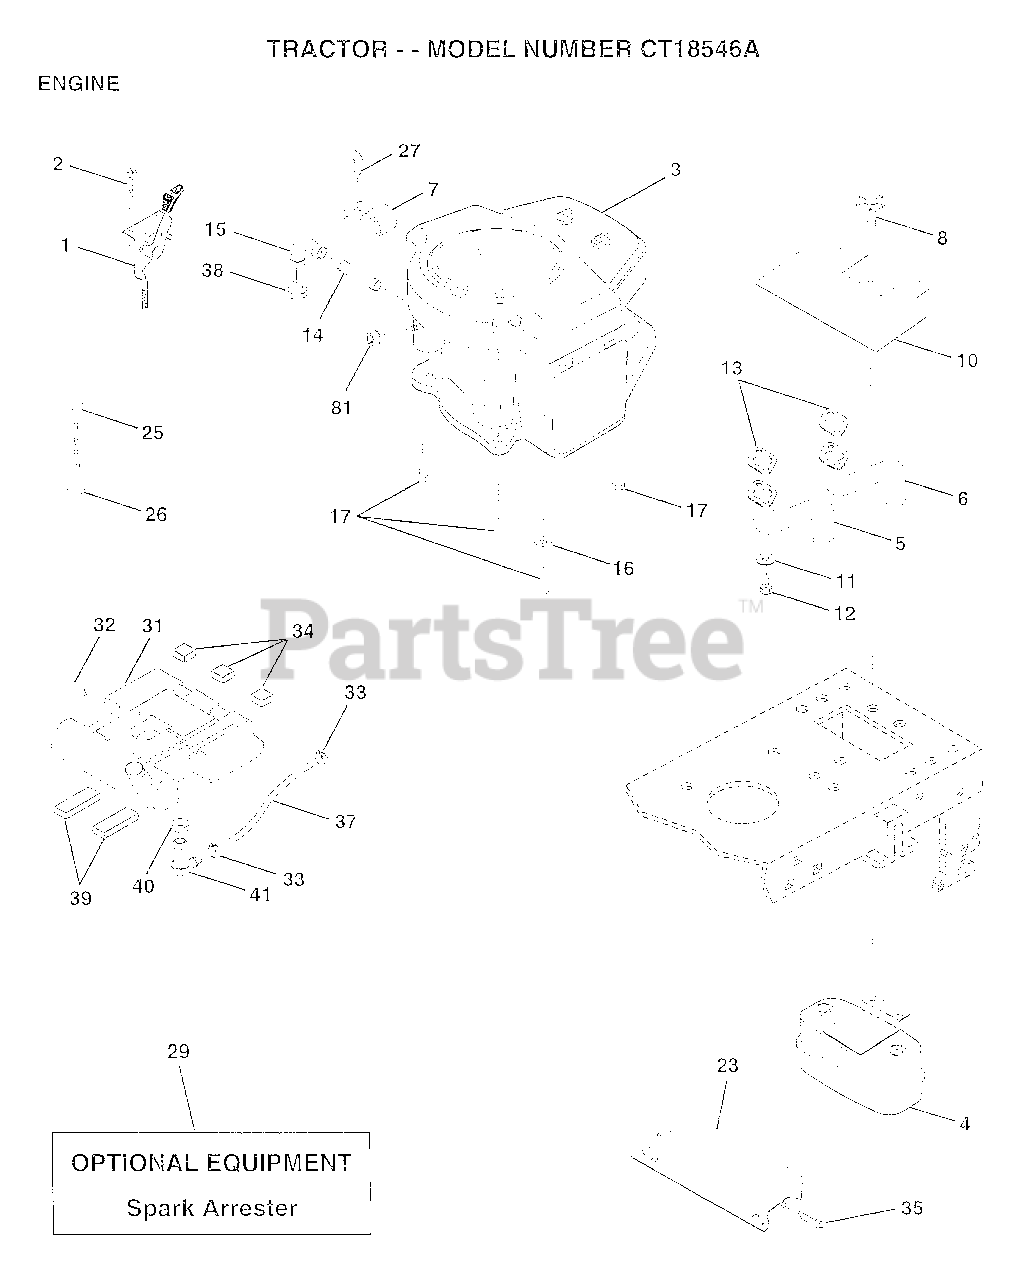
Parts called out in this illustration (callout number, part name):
2	SCREW LT
3	ENGINE, BRIGGS
4	MUFFLER.TW.LOTONE
5	EXHAUST.B&S.18.LH
6	EXHAUST.B&S.18.RH
7	CLAMP.TUBE.DBL.EN
8	BOLT.5/16-18.UNC
10	SHIELD.HEAT.
11	LOCKWASHER
13	GASKET MUFFLER
14	PIPE NIPPLE LT
15	ELBOW
16	LOCKWASHER
17	SCREW LT
23	SHIELD-HEAT
25	"CONTROL.CHOKE.51"""
26	"NUT,KEPS 3/8-24IM"
27	"SCREW-TT,10-32 FL"
31	TANK FUEL REAR
32	CAP ASM FUEL
33	HOSE CLAMP
34	PAD-SPACER LT
35	SCREW
37	FUEL LINE T
39	PAD IDLER TI
40	BUSHING OUTLET T
41	STEM.TANK.FUEL
81	NUT
